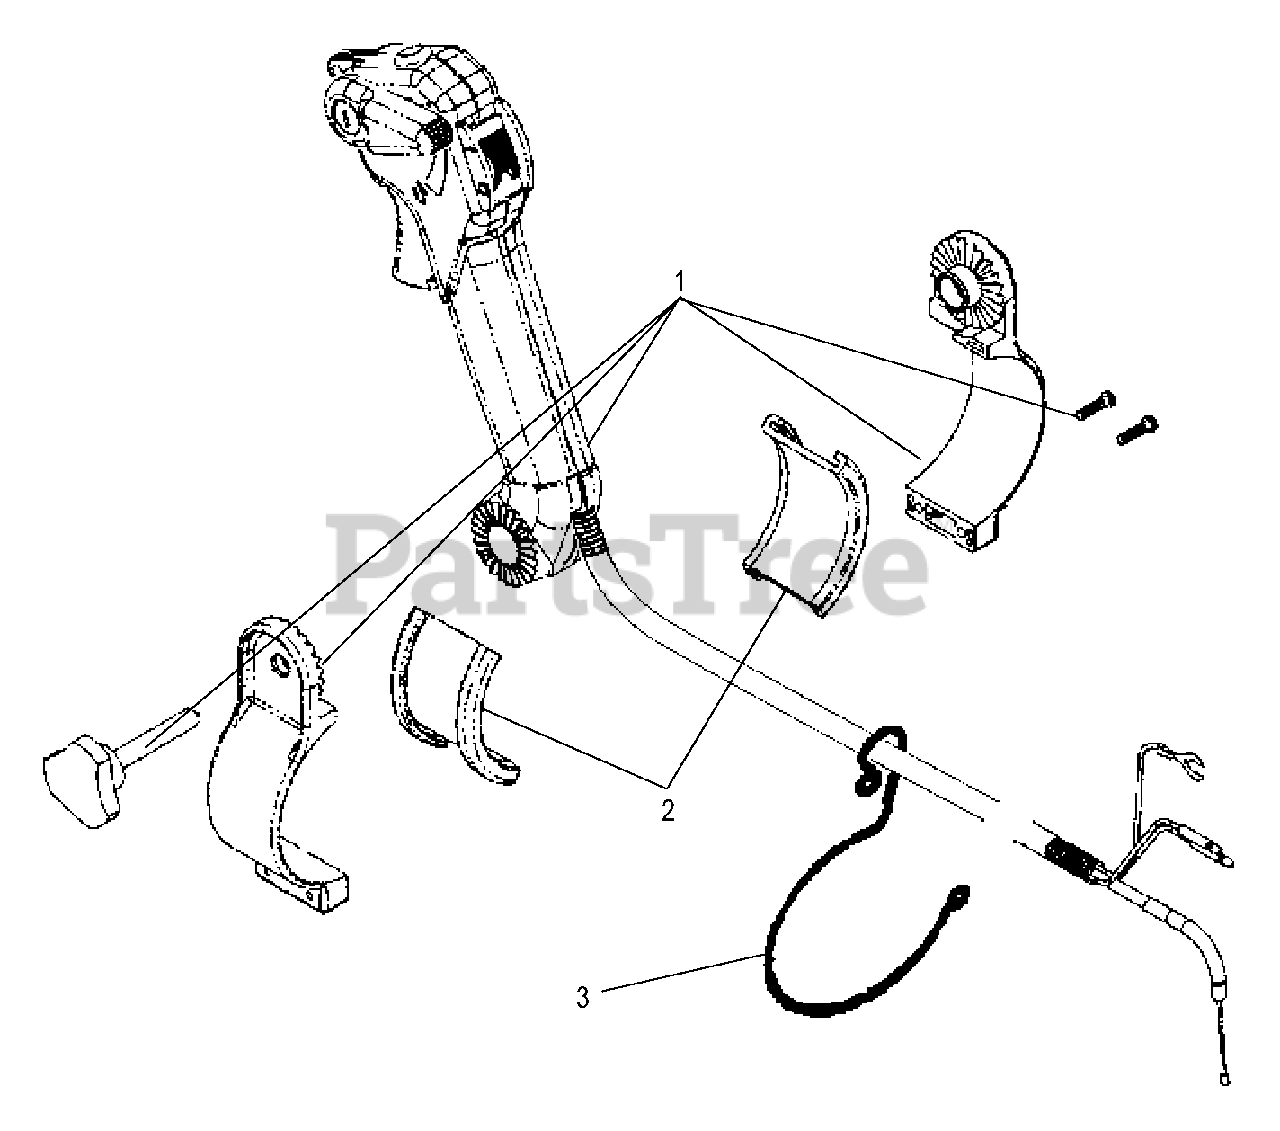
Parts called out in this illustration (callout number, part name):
1	THROTTLE LEVER ASSY
2	SPACER
3	CLAMP
